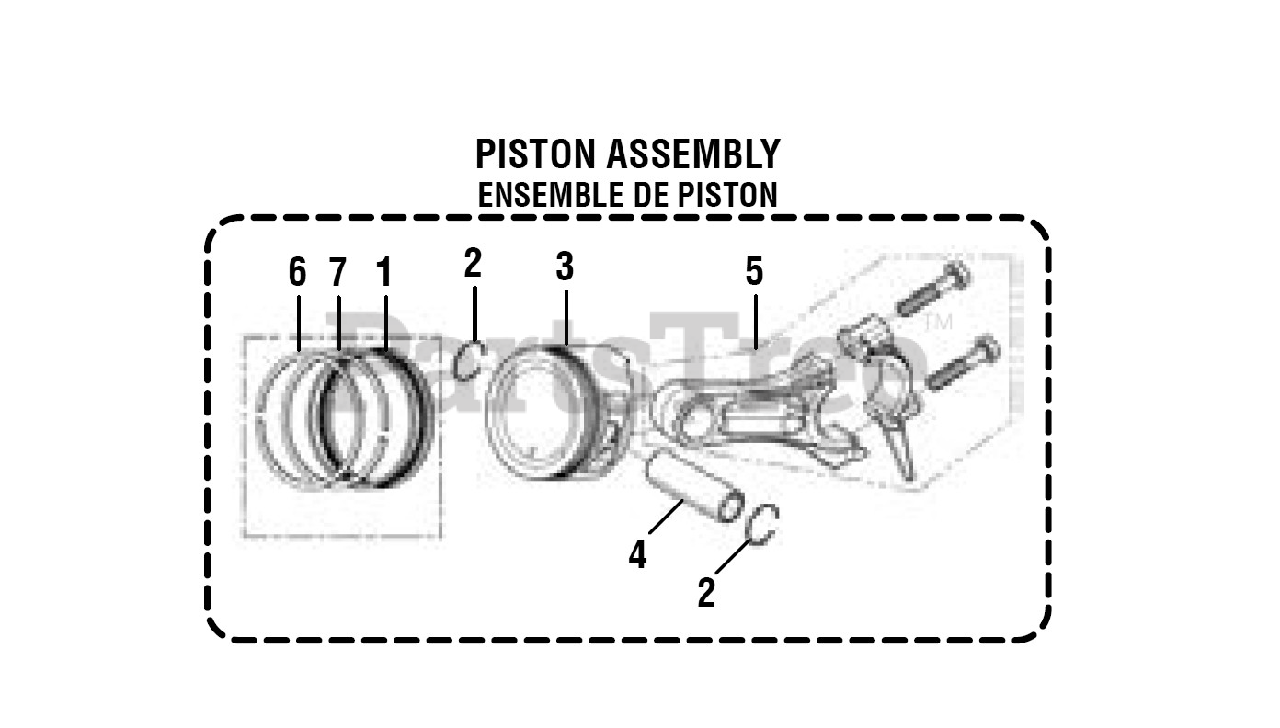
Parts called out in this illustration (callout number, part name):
1	Oil Ring Kit
2	Piston Pin Clip
3	Piston
4	Piston Pin
5	Connecting Rod
6	The First Ring
7	The Second Ring
